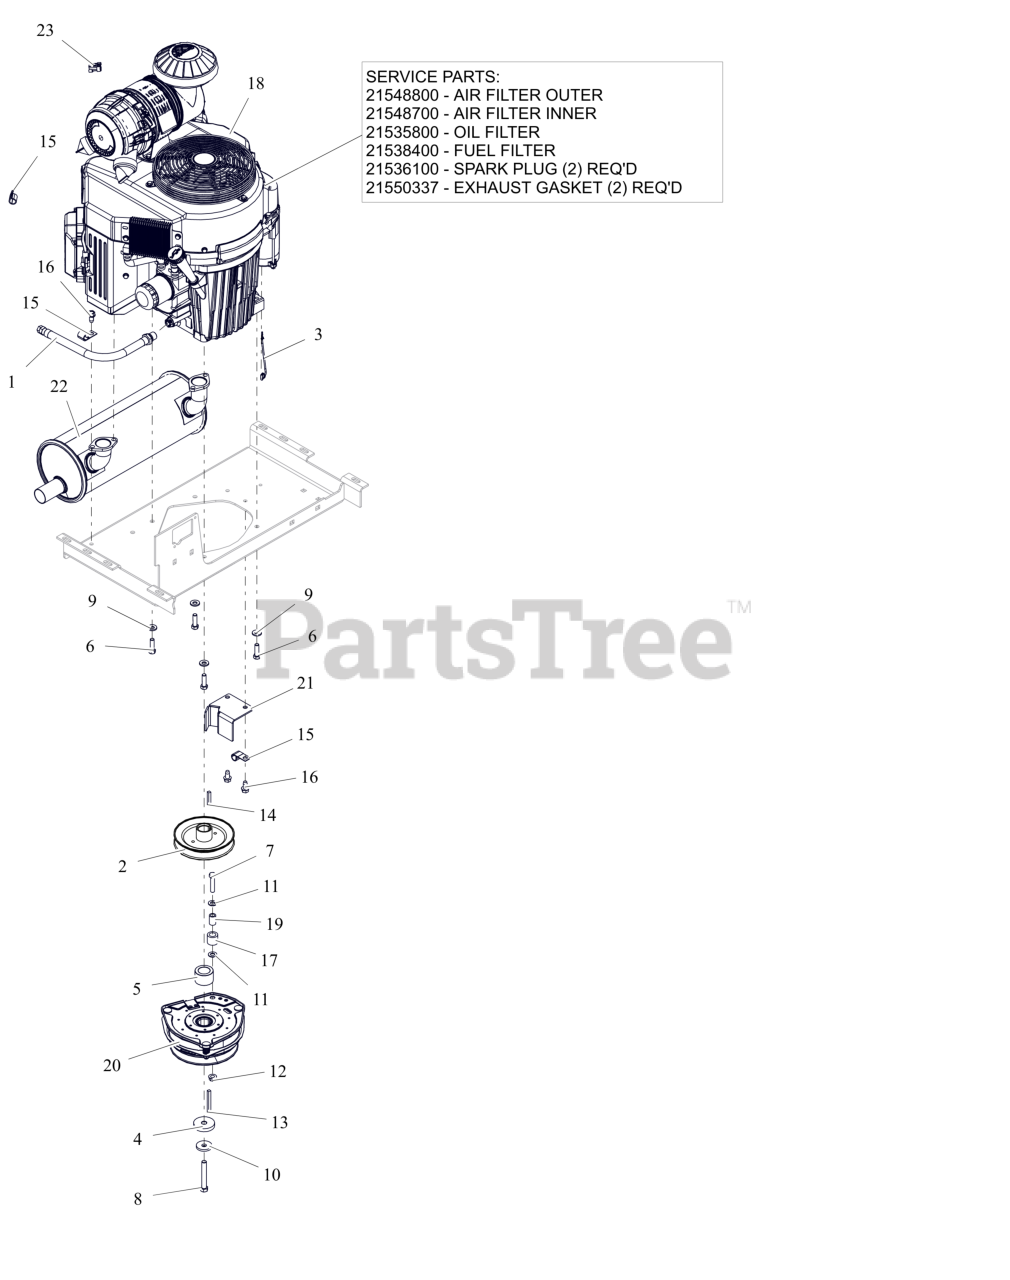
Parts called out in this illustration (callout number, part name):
1	HOSE, OIL DRAIN
2	WLDMT, TRANSAXLE DRIVE PULLEY
3	LEAD - STARTER SOLENOID
4	SPACER, .474/.459X2.00X.350
5	SPCR, 1.125 x 1.750 x 1.147
6	BLT, HEX .38-16X1.25 G5 ZCC NT
7	BLT, HEX .38-16X1.75 G5 ZCC
8	BLT, HEX 0.4375-20X3 G8 ZCC NT
9	WASHER, 3/8" SPRING DISC
10	WASHER, 7/16" SPRING DISK
11	WSHR,FLT .406X.812X.065 ZCC
12	NUT-LK-CTR-FLG .375-16 GF ZCC
13	KEY-SQ .25 X 2.50 X .25 SAE
14	KEY-SQ .25 X 1.50 X .25 SAE
16	SCR,TAP .375-16X.75 HWH TR ZCC
17	BUMPER,RUBBER .62X1.0X.88 LG
18	ENGINE - KAWASAKI FX1000
18	FILTER, OUTER
18	FILTER, INNER - KAW
18	FILTER,OIL - KAW
18	FUEL FILTER - KAWASAKI
18	PLUG, SPARK
18	GASKET, EXHAUST (11061-7061)
19	BUSH.,S.391X.622X.950 ST
20	CLUTCH, OGURA GT3.5-AR04
21	WLDMT, CLUTCH STOP (BLACK)
22	MUFFLER - 34HP KAWASAKI VERT.
23	CLIP, T, .38-.50
